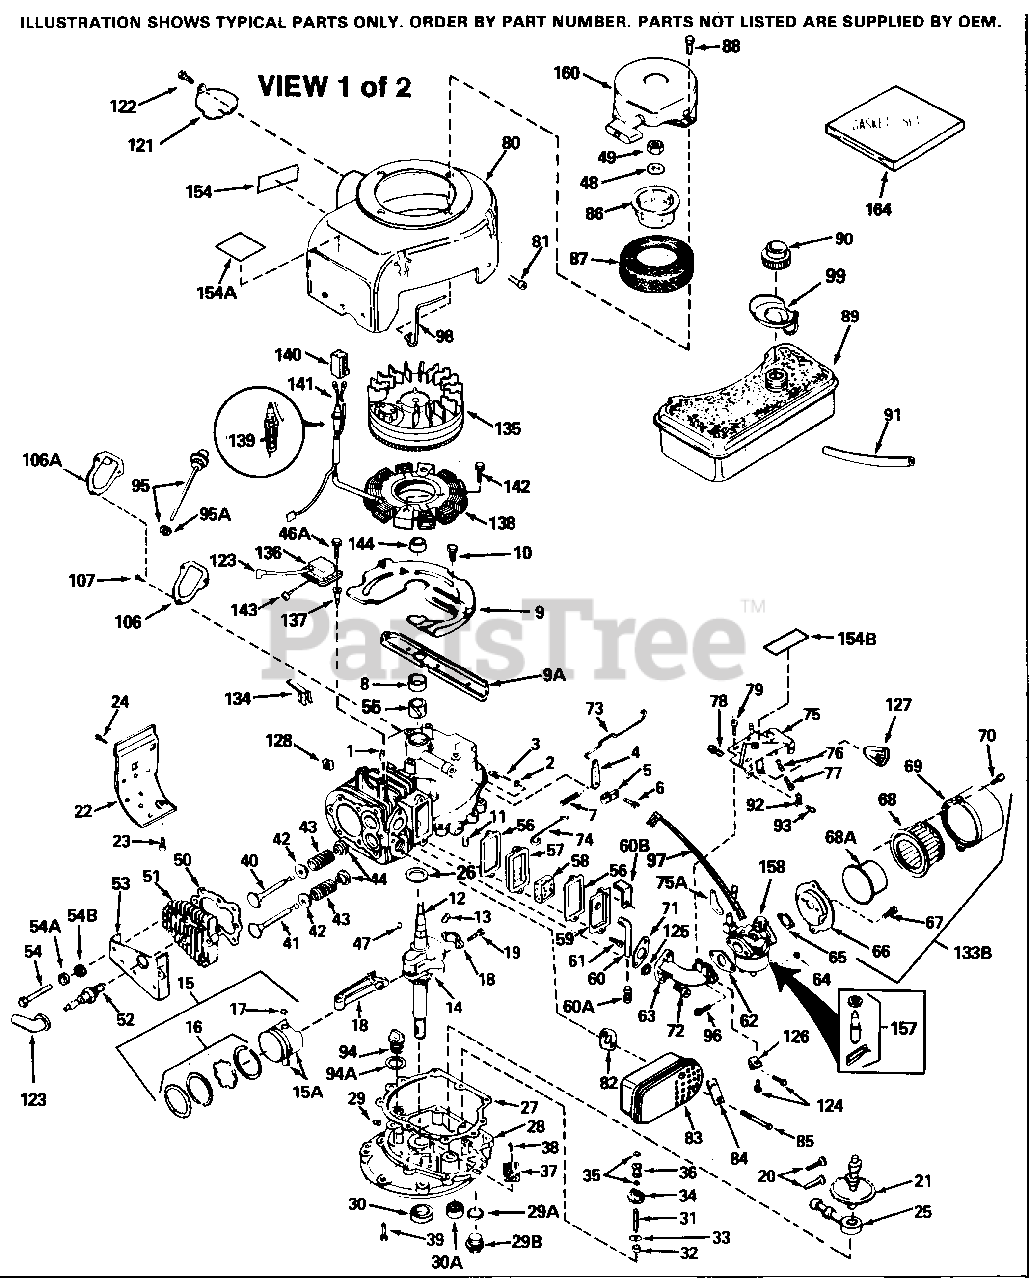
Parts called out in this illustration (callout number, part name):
1	"Cylinder (Incl. 8, 11, 94 & 94A) 2-5 /8"
2	Flat Washer
3	Rod, Governor
4	Lever, Governor
5	Clamp, Governor lever
6	Screw, 8-32 x 5/16"
7	Spring, Governor
8	Seal, Oil
9	Blower Housing Baffle ed)
9	Blower Housing Baffle eq.)
10	Screw, 1/4-20 x 5/8"
11	Dowel Pin
12	Crankshaft (Incl. 13 & 14)
13	Pin, Crankshaft gear
14	Gear, Crankshaft
15	Piston, Pin & Ring Set (2-5/8") Std.
15	Piston, Pin & Ring Set (.010" OS)
15	Piston, Pin & Ring Set (.020" OS)
15A	Piston & Pin Ass'y. (Incl. 17) (2-5/8 ") (Std.)
15A	Piston & Pin Ass'y. (Incl. 17) .010" OS
15A	Piston & Pin Ass'y. (Incl. 17) .020" OS
16	Ring Set (2-5/8") (Std.)
16	Ring Set (.010" OS)
16	Ring Set (.020" OS)
17	Piston Pin Retaining Ring
18	Rod Assy., Connecting (Incl. 19)
19	Bolt, Connecting rod (Incl. 2 pieces)
20	Lifter, Valve
21	Camshaft (MCR)
22	Extension, Blower housing
23	Screw, 10-24 x 1/2"
24	Screw, 1/4-20 x 1/2"
25	Pump Assy., Oil
27	* Gasket, Cylinder cover
28	Flange Ass'y. Incl. 29,30,31,33,182 & 183
29	Oil Drain Plug (Sq. hd., 1/4-18)
30	Oil Seal
31	Shaft, Mech. Governor
32	Governor Spacer Assy. (Incl. 33)
33	Washer, Flat (2 required)
34	Gear Assy., Governor
35	Retaining Ring
36	Spool, Governor
37	Screen, Oil filter (Use as required)
38	Screw, 8-32 x 5/16" (Use as required)
39	Screw, 1/4-20 x 1-1/4"
40	Intake Valve (Std.) (Incl. 44)
40	Intake Valve (1/32" OS) (Incl. 44)
41	Exhaust Valve (Std.)(Incl. 151)
41	Exhaust Valve (1/32" OS) (Incl. 151)
42	Valve Spring Cap
43	Valve Spring
44	Cap, Lower valve spring
47	Key, Flywheel
48	Washer, Belleville
49	Nut, Washer, 1/2-20
50	* Gasket, Head
51	Head, Cylinder (Incl. 54)
52	Resistor Spark Plug - RJ17LM
52	Resistor Spark Plug (RJ-17LM)
53	Cover Assy., Cylinder head
54	Screw, 5/16-18 x 2" (Use as required)
54	Screw, 5/16-18 x 2-1/2" Use as requir ed
54A	Washer, Belleville (Use as required)
54B	Washer, Flat (Use as required)
56	* Gasket, Breather cover
57	Breather Body
58	Breather Element
59	Valve Cover
60	Tube, Breather
61	Screw, 10-24 x 1/2"
62	* Gasket, Carburetor
63	Pipe, Intake
65	* Gasket, Air cleaner
66	Bracket, Air cleaner
67	Screw, 10-32 x 1/2"
68	Air Filter (Paper) also available in Packaged Part #740029B
69	Body, Air cleaner
70	Screw, 8-32 x 3/8"
71	* Gasket, Intake to cylinder
72	Screw, 5/16-18 x 1-1/8"
73	Link, Throttle
74	Link, Governor spring
75	Control Assy., Speed Incl. 76, 77 & 7 8
76	Spring, Compression
77	Screw, 5-40 x 7/16"
78	Terminal Ass'y. (Use as required)
79	Screw, 10-24 x 9/16"
80	Blower Housing (Incl. 121 & 122) Elec . Str.
81	Screw, T-40, 5/16-24 x 21/32"
82	* Gasket, Exhaust
83	Muffler
84	Plate, Muffler locking
85	Screw, 5/16-18 x 3/4"
85	Screw, 5/16-18 x 2-3/4" Use as requir ed
85	Screw, 5/16-18 x 2-1/2" Use as requir ed
86	Cup, Starter
87	Starter Screen
88	Screw, 1/4-28 x 7/16"
90	Fuel Cap (Red 1-1/2" ID) also availab le in Packaged Part #740005B
90	Fuel Cap (Use as required)
91	Fuel Line (8.62")
91	Fuel Line (32") (Use as required)
95	Dipstick (Incl. 95A) NOTE: Some mode ls are equipped with three oil fill l ocations, two in cylinder and one in mounting flange.When replacing dipsti cks, be sure to order correct style.
95A	"O" Ring
96	Screw, 1/4-28 x 7/8" Use as required
96	Screw, 1/4-20 x 13/16" Use as requir ed
97	Ground Wire
98	Clamp, Tank hold down
123	Spark Plug Cover
123	Cover, Spark plug (Use as required)
127	Knob, Speed control
133B	A/C Assy. Incl. 65,66,67,68A,69,70,13 4
154	Decal, Instruction
154B	Decal, Speed control
160	Rewind Starter Refer to Division 5, S ection C, page 25 for breakdown
164	* Gasket Set (Incl. items marked *)
